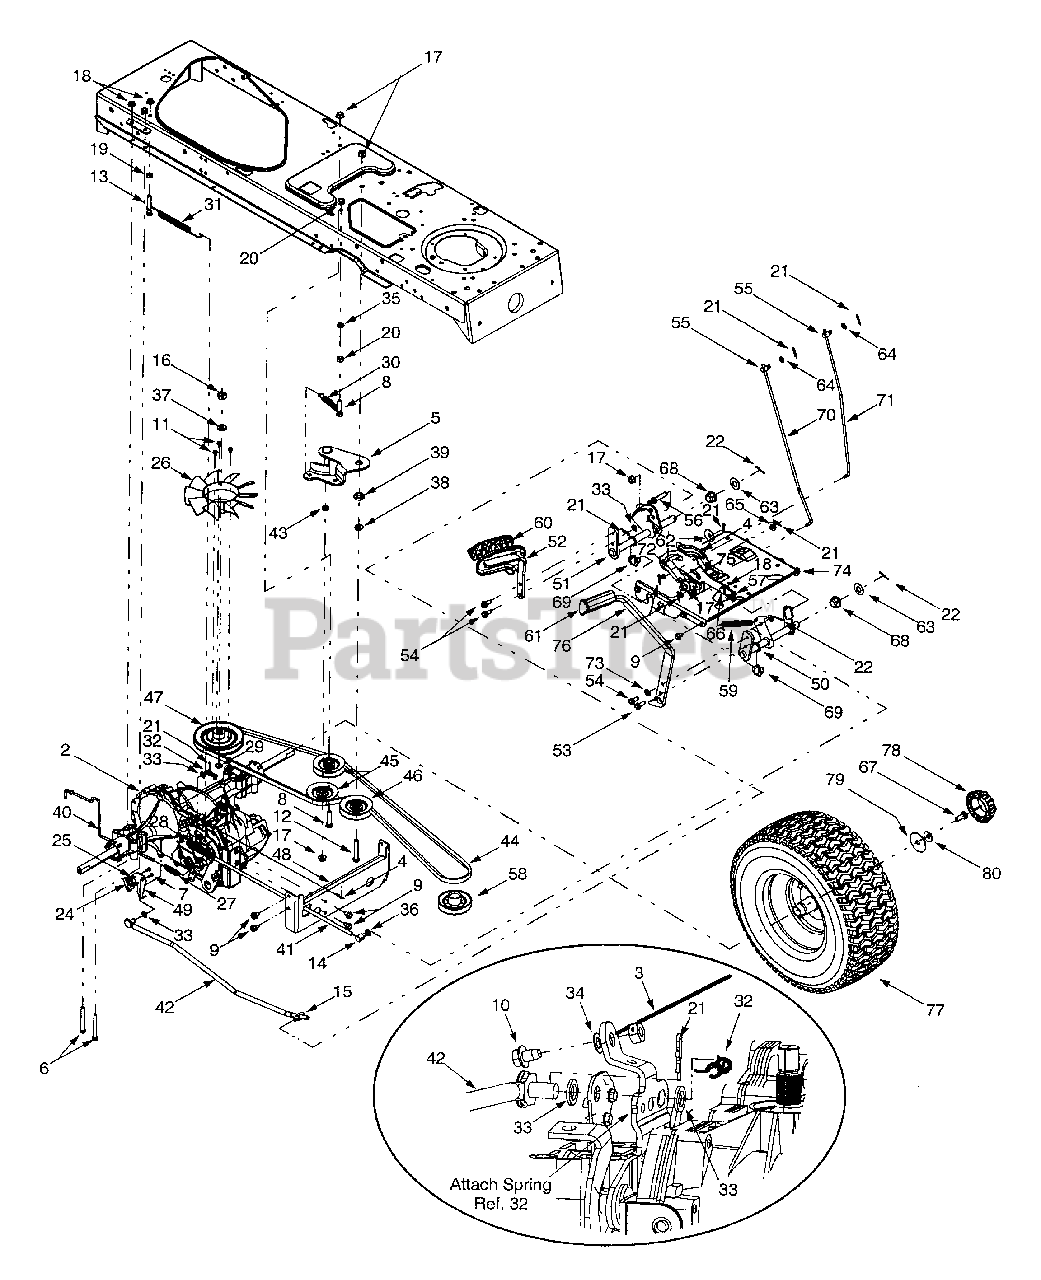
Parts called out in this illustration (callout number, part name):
1	Transaxle Mounting Bracket
2	Hydrostatic Transmission
3	Reverse Wire Harness Adapter & Ground
4	Neutral Return Bracket
5	Double Idler Bracket Assembly
6	Hex Cap Screw, 5/16-18 x 2.75
7	Screw, #8-18 x .5
8	Hex Cap Screw, 3/8-16 x 1.5
9	Self-tapping Screw, 5/16-18 x .625
10	Self-tapping Screw, 1/4-20 x .375
11	Screw, #12-24 x .375
12	Hex Cap Screw, 3/8-16 x 2.25
13	Hex Cap Screw, 5/16-18 x 2.0
14	Ferrule, 5/16-18
15	Ferrule, 3/8-24
16	Hex Nut, 1/2-20
17	Flange Lock Nut, 3/8-16
18	HEX FLANGE NUT
19	Hex Nut, 5/16-18
20	Hex Nut, 3/8-16
21	Internal Cotter Pin
22	Cotter Pin
23	Cable Tie
24	SAFETY SPRING SWITCH
25	Insulator Nut Plate
26	10-inch Fan
27	Extension Spring, .48 x 2.03
28	Extension Spring, .59 x 4.0
29	Wire Ring
30	Extension Spring, .5 x 3.97
31	Extension Spring, .5 x 7.0
32	Extension Spring, 3/8 x 1.44
33	Flat Washer, .385 x .62 x .063
34	Flat Washer, .281 x .50 x .063
35	Lock Washer, 3/8
36	Flat Washer, .344 x .688 x .065
37	Lock Washer, 1/2
38	Flat Washer, .407 x .812 x .135
39	Shoulder Spacer, .38
40	Hydrostatic Bypass Rod
41	Hydrostatic Brake Rod
42	Hydrostatic Control Rod
43	Spacer, .376 x .625 x .22
44	Drive Belt
45	V idler Pulley, 3.06
46	Flat Idler Pulley, 2.75
47	Input Pulley, 5.0
48	Transmission Torque Bracket
49	Switch Actuator Bracket
50	Brake Control Assembly
51	Drive Control Assembly
52	Hydro Pedal Assembly
53	Self-tapping Screw, 5/16-18 x .875
54	Self-tapping Screw, 5/16-18 x .75
55	ADJUSTMENT FERRULE 1/4-20 x 1.00
56	Pin, 3/8-16 x 2.43
57	Compression Spring, .34 OD x 1.0
58	Engine Pulley
59	Extension Spring, .50 OD x 6.37
60	Drive Pedal Pad
61	Brake Pedal Pad
62	Flat Washer, .411 x 1.25 x 1.0
63	Flat Washer, .64 x 1.24 x .06
64	Flat Washer, .344 x .062 x .03
65	Flat Washer, .406 x .875 x .105
66	Shoulder Screw, .437 x 1.62
67	Hex Cap Screw, 5/16-24 x .75
68	Hex Flange Bearing
69	Split Hex Flange Bearing
70	Cruise Control Rod
71	Brake Lock Control Rod
72	Cruise Latch
73	Flat Washer, .344 x .750 x .120
74	Steering Support Bracket
75	Drive Lockout Bracket
78	Deluxe Hub Cap (Ref. 79 Required)
79	Flat Washer, .350 x 1.59 x .062
80	Bell Washer, .34 x .872
